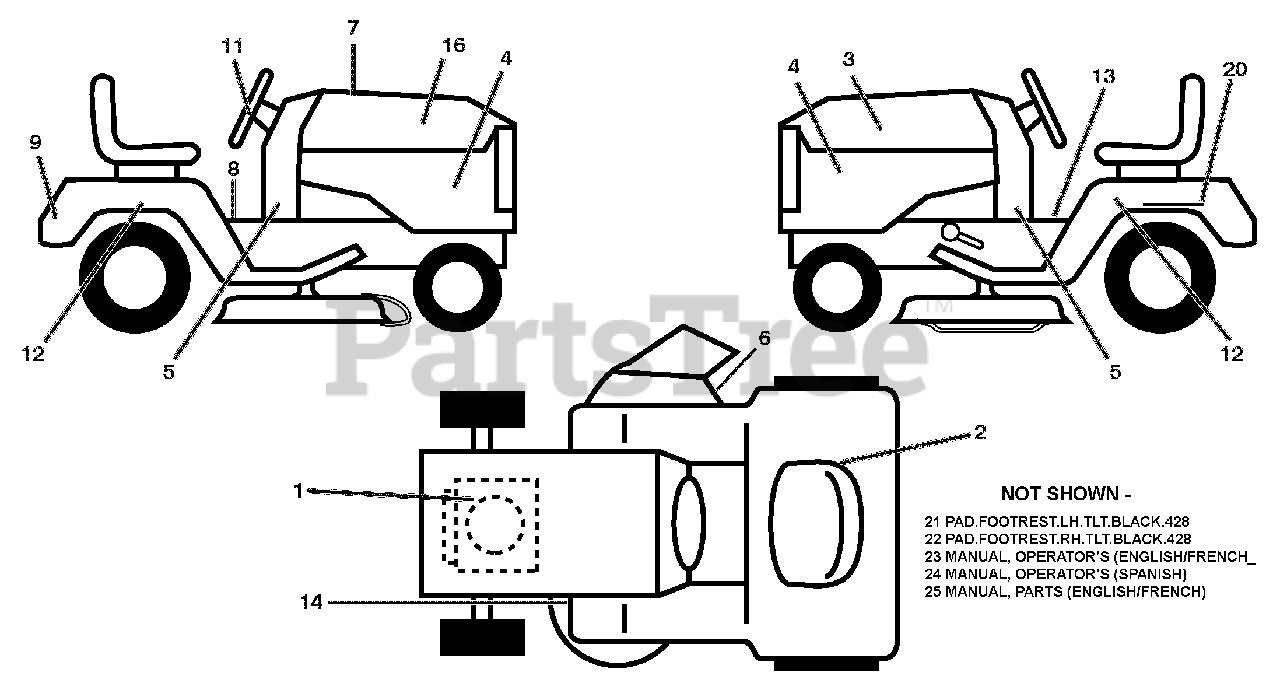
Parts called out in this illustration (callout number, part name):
1	Decal Engine H.P.
2	Decal Fender Service
3	DECAL.HOOD.LH.3HIGH.ARIENS
4	Decal, Side Panel
5	DECAL.DASH.LWR.18HP.ARIENS
6	DECAL.MOWER.WARN.KEEP HAND AWY
7	DECAL.RPL.KH(SNGL).TLW.42.PMST
8	DECAL.FENDER.WARNING.ENG/FR.07
9	Decal, Fender
11	DECAL.WHEEL.STEER.ARIENS
12	DECAL.FENDER.SIDE.HYDRO.ARIENS
13	Decal, Flag
14	DECAL.V-BELT.SCH.42/46"MEC/ELE
16	DECAL.HOOD.RH.3HIGH.ARIENS
20	DECAL.BAT.DAN/POI P/L SYM.WPN
